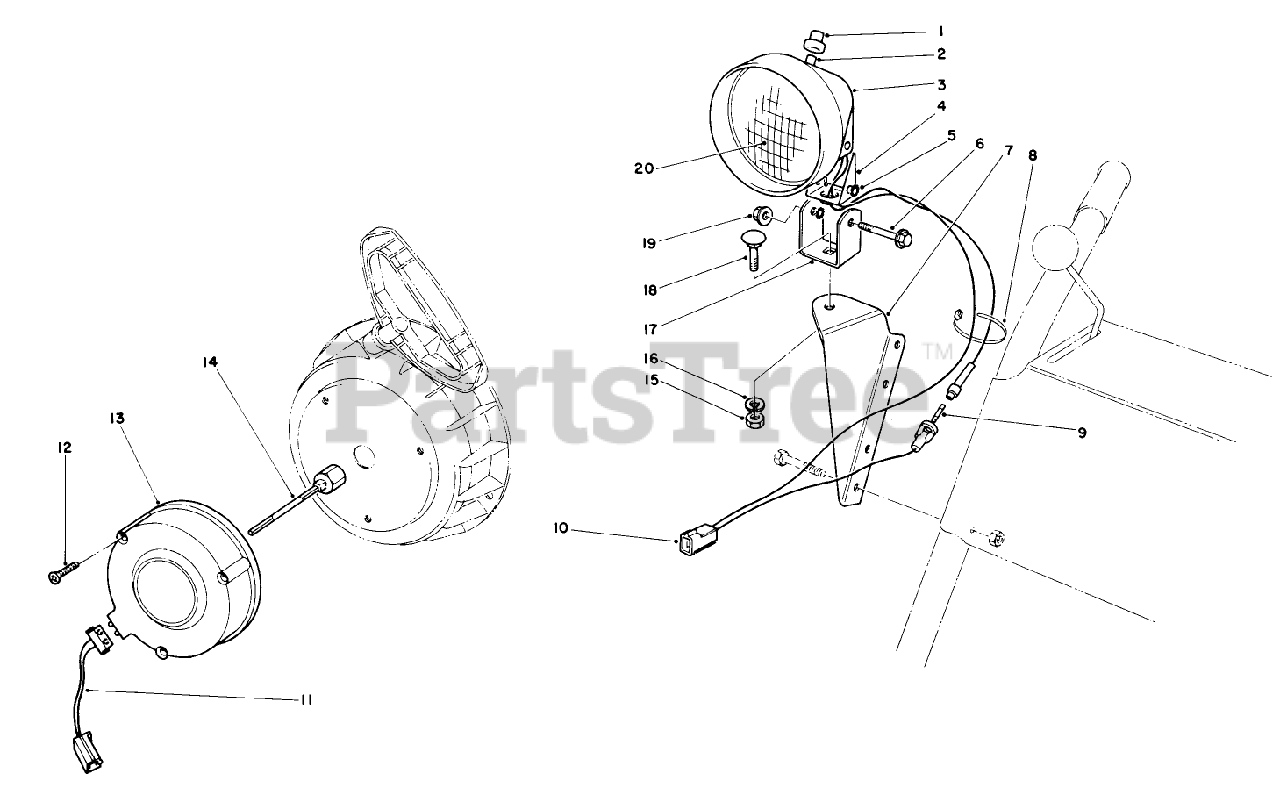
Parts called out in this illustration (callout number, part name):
1	BOOT-SWITCH
5	WASHER-LOCK
6	SCREW-HH
7	MOUNT-LAMP
8	TIE-CABLE
9	Fuse-71/2 Amp.
10	WIRE ASM
13	TECUMSEH 1A183-69
14	TECUMSEH 1A52-194
15	NUT-HEX
16	WASHER-LOCK
18	BOLT-CARR
19	NUT-HF
20	BEAM-SEALED
